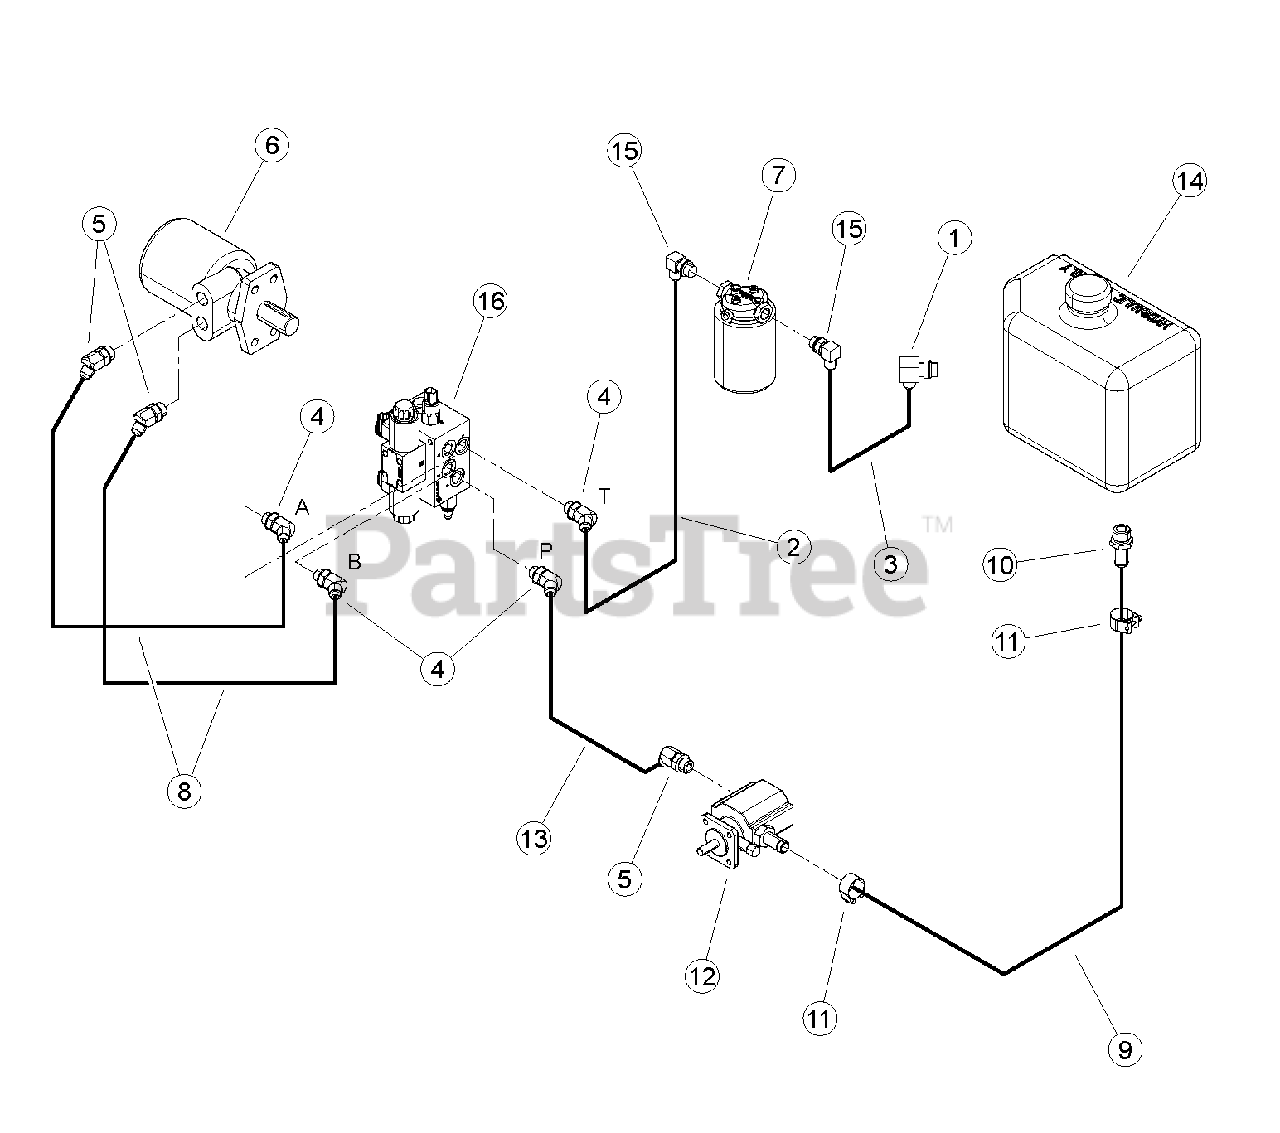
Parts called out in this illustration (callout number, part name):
1	ADAPTER, -10MORING/-8MJIC 90 DEG
2	HYD. HOSE ASSEMBLY., 2X-8FMJICSW
3	HOSE ASSEMBLY, 8FMJIC/8FMJIC SW X 32"
4	ADAPTER, -8MORB/-8MJIC 45
5	ADAPTER, -10MORING/-8MJIC 45 DEG
6	MOTOR, 45 CU IN HYDRAULIC
7	ASSEMBLY, HYDRAULIC FILTER
8	HOSE, .375 X 36 -8FMJIC/-8FMJIC
9	HOSE, .75 ID X 21 IN 100R4 HYD
10	ADAPTER, -10 MORB/-12 HOSE BARB
11	CLAMP, 1-5/32 TO 7/32 OD RANGE T-BOLT
12	PUMP, 2 STAGE CW HI/LO 0.605 DISP.
13	HOSE, .50 X 48 -8FMJIC/-8FMJIC
14	TANK, HYDRAULIC
15	ADAPTER, -8MORING/-8MJIC 90 DEG
16	ASSEMBLY, HYDRAULIC FEED FLOW VALVE W/ PS
